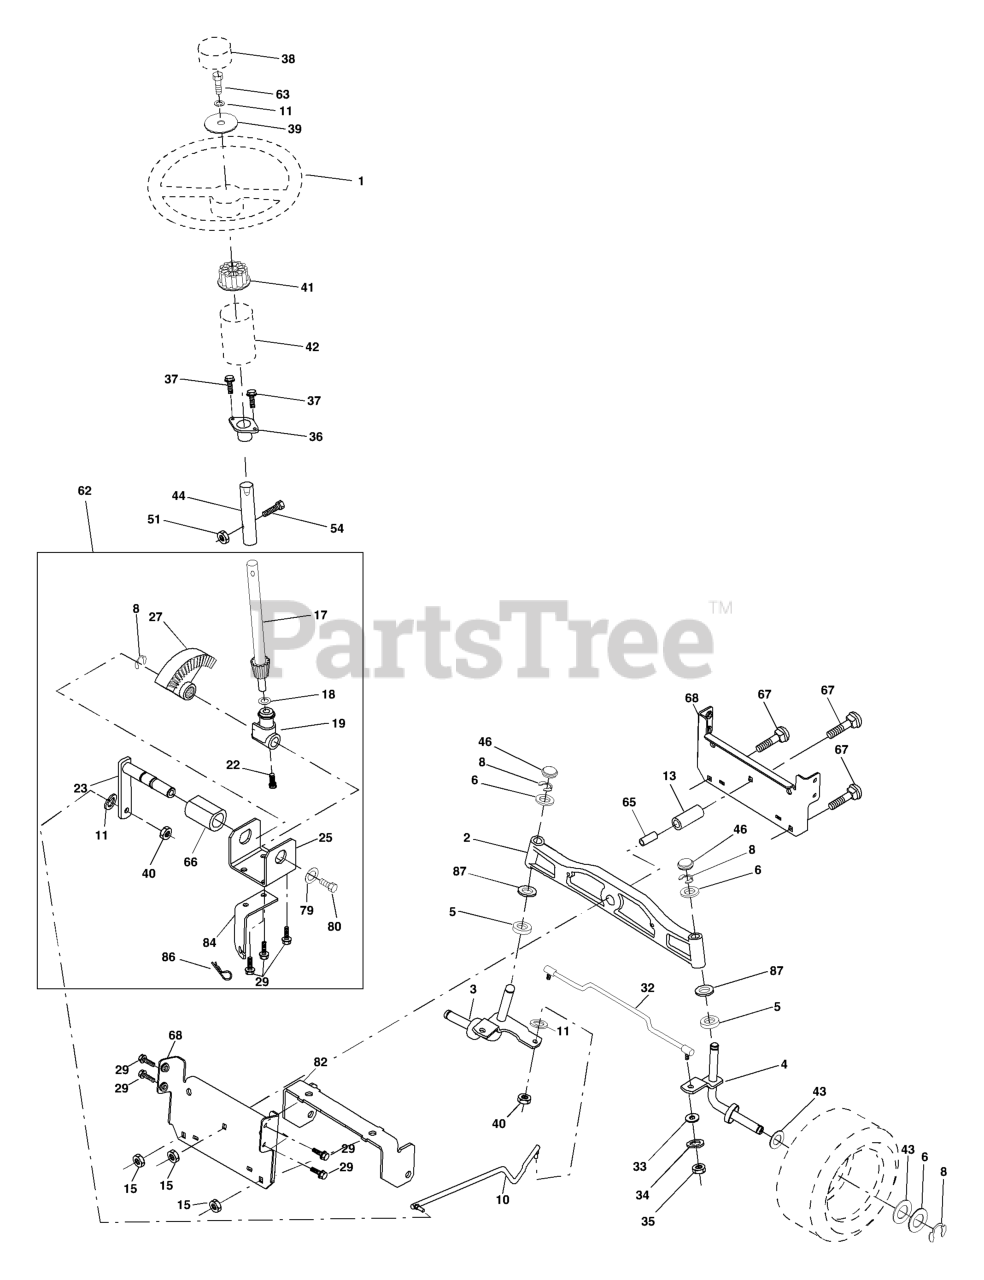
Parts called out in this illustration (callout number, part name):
1	STEERING WHEEL
2	AXLE ASM
3	SPINDLE.ASM.LH.15"TIRES
4	SPINDLE.ASM.RH.15"TIRES
5	THRUST WASHER
10	DRAGLINK.15".TIRES
11	WASHER, LOCK 3/8
13	TUBE, PIVOT AXLE
15	NUT
17	SHAFT ASM STEERING
18	THRUST WASHER
19	STEERING SHAFT SUPPORT
22	SCREW.HX.WSH.HD
23	SHAFT ASSY PITTMAN
25	BRACKET STEERING
27	GEAR.SECTOR
29	SCREW 3/8-16X3/4
32	ROD.ASM.TIE.BALL.JOINT.NOVAN
33	WASHER M
34	WASHER.LOCK.HVY.HLCL.SPR.5/16
35	NUT, CROWNLOCK
36	BUSHING, STEERING
37	SCREW.TT.#10-32X.5.3/8.FLANGE
38	CAP.WHEEL.STEERING.GREY
39	Washer 13/32 x 1-1/20 x 11 Gauge
40	GRIPCO NUT
41	STEERING WHEEL ADAPTOR
42	BOOT STEERING
44	EXT SHAFT STEERING
46	CAP.SPINDLE.BLACK
51	NUT.71038.31-18.HEX.NYLOCK
54	BOLT.5/16-18X1-1/4 FULL.THREAD
62	Kit, Steering Assembly, Service
63	BOLT
65	SPACER BRACE AXLE
66	BEARING ARM
67	BOLT
68	BRACE.AXLE.15"TIRES
79	WASHER
80	BOLT.HX.NYLON3/8-16X
82	BRACKET
84	Bracket Cable Clutch Chassis
86	SPRING.RETAINER.YELLOW.ZINC
87	WASHER, FLAT .781 X 1 1/2"
